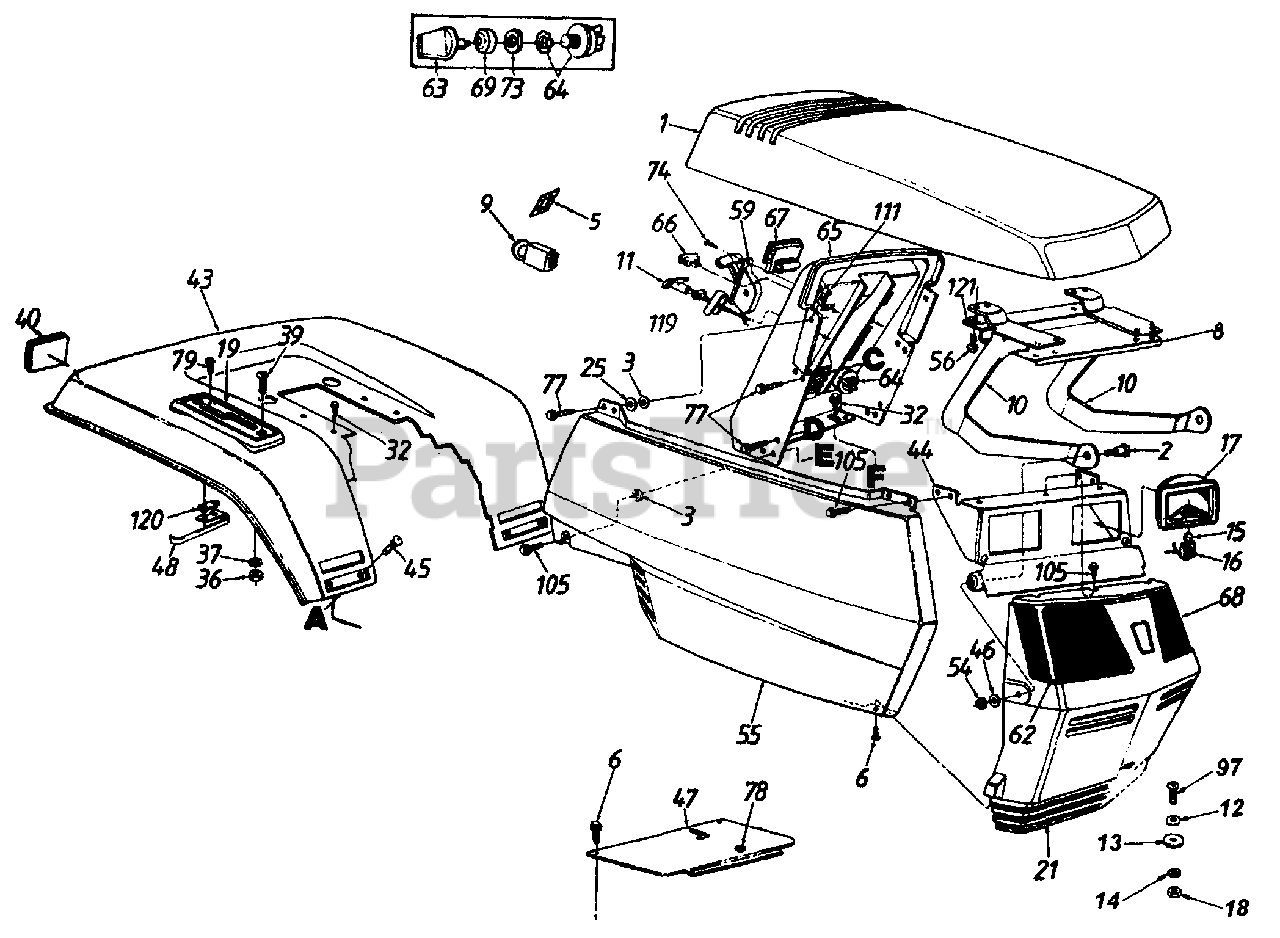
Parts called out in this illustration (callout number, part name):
1	Hood Ass'y.
2	Shld. Bolt .437" Dia. x .35"
3	Bolt Retainer 1/4" I.D.
5	Switch Retainer
6	Truss Mach. B-Tap Scr. #10 x .5" Lg.
12	Fl-Wash. .34" I.D. x 1" O.D.
13	Speed Nut
14	L-Wash. 5/16" I.D.
15	Lamp
16	Twist Lock-Lamp Socket
17	Headlight Housing
18	Hex Nut 5/16-18 Thd.
19	Speed Control Index Brkt.
21	Grille
25	Fl-Wash. 1/4" I.D. x .93" O.D.
32	Hex Wash. Hd. AB-Tap Scr. 5/16 x .75" Lg.
39	Truss Mach. Scr. 1/4-20 x 1.0" Lg.
40	Reflector
46	Fl-Wash. .328" I.D. x .68" O.D.
54	Hex Cent. L-Nut 5/16-18 Thd.
55	Side Panel Ass'y.
56	Hex Wash. Hd. B-Tap Scr.1/4 x .5"
62	Lens-R.H.
63	Ignition Key
64	Ignition Switch
65	Dash Panel
67	Ammeter
68	Lens-L.H.
69	Ignition Switch Cap
73	Ignition Switch Nut
74	Truss Mach. AB-Tap Scr. #10 x .5" Lg.
77	Hex Wash. Hd. Tap Scr. 1/4 x .75" Lg.
78	Snap Bushing
97	Hex Bolt 5/16-18 x .75" Lg.
105	Hex Tap Scr. 1/4-20 x .5" Lg.
111	Speed Nut 1/4-20 Thd.
119	Retainer Clip
120	Insulator Nut Plate
